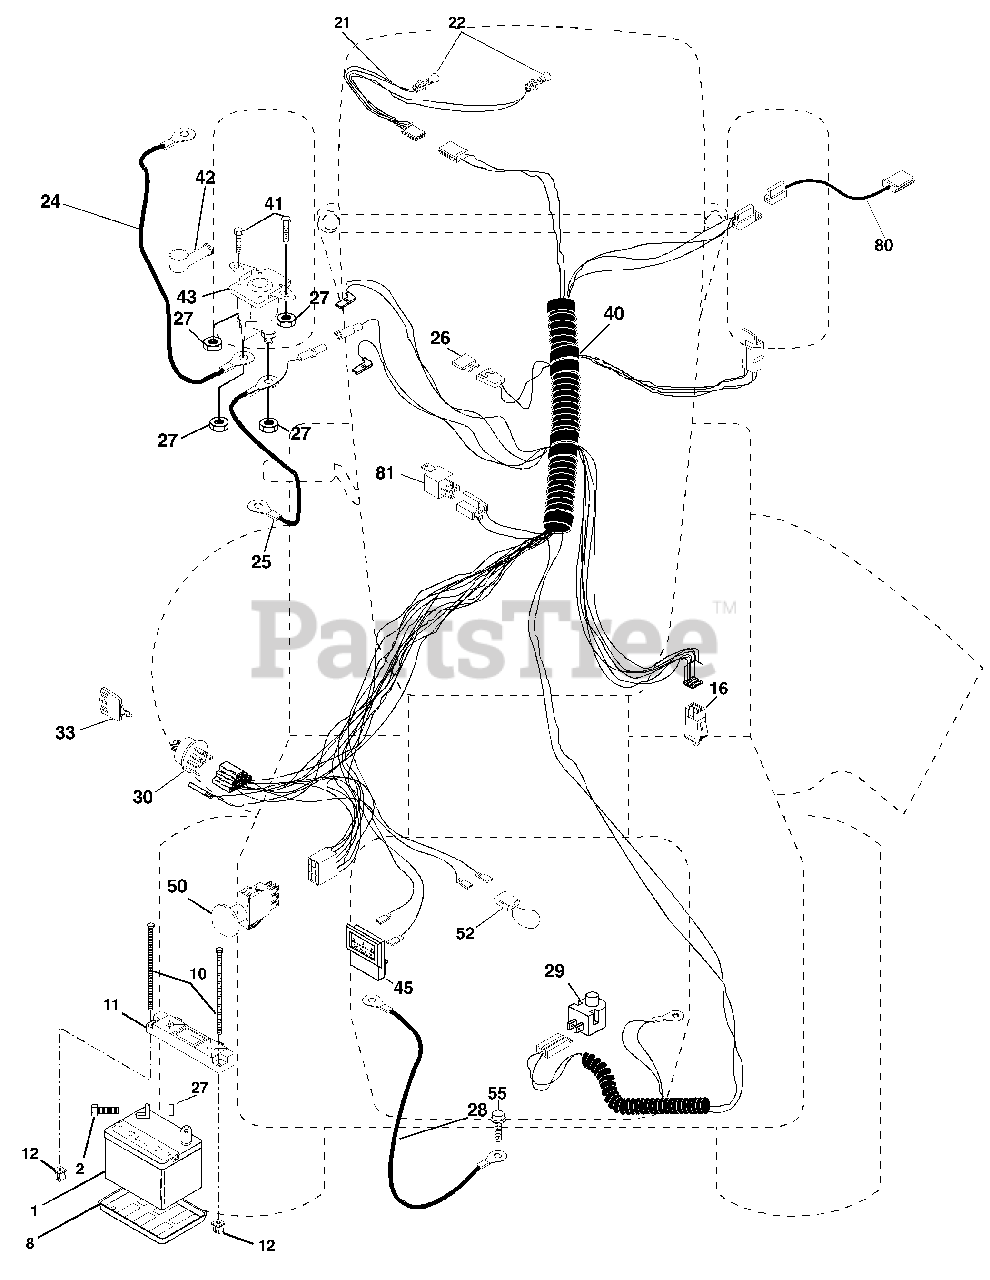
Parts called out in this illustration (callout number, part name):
1	Battery
2	Bolt Hex Hd 1/4-20 UNC X 3/4
8	Tray, Battery
10	Bolt, BTR FRT 1/4-20 x 7.5
11	Hold Down Battery, Front
12	Nut, Push, Nylon
16	Switch Interlock Push-In
21	Harness Asm Light W/4152j
22	Bulb Light #1156
24	Cable Battery 6 Ga 11" red
25	Cable Batterywire
26	Fuse 15 AMP
27	Nut Keps Hex 1/4-20 Unc
28	Cable Ground
29	Switch Plunger Normal OP Olive
30	Switch Ign 4 pos w/lights
33	Key Ign
40	Harness Ign.
41	Bolt Blk Fin Hex 1/4 - 20 x 1/2
42	Cover Terminal Red
43	Solenoid
45	Ammeter Rectangular
50	Switch, PTO 3PDT
52	Protection Wire Loop
55	Screw Thdrol 5/16-18 x 1/2
80	Harness, Clutch EVX
81	Relay Asm
